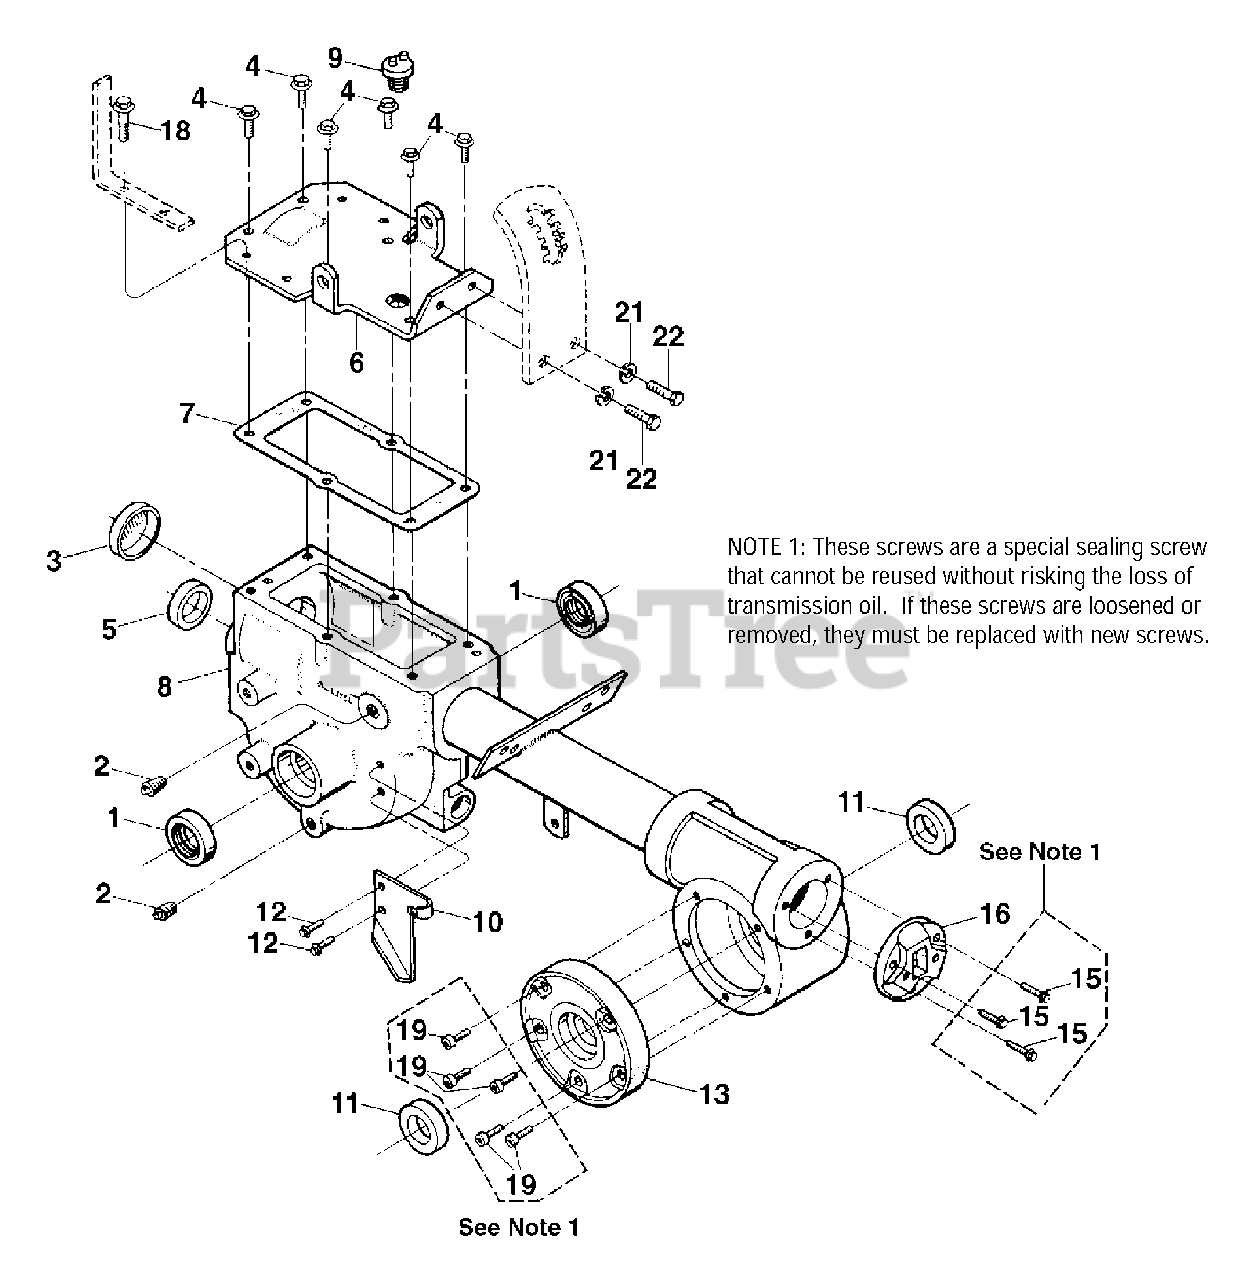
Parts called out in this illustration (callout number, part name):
1	Oil Seal (Double Lip), Wheel Shaft
2	Pipe Plug, 1/4,
3	Seal, Transmission Bore
4	Hex Flange Screw, 5/16-18 x 3/4
5	Oil Seal, Input Pinion Shaft
6	Transmission Cover
7	Gasket, Transmission Top Cover
8	Transmission Case Assy
10	Mounting Plate, Wheel Clutch Cable
11	Oil Seal, Tiller Shaft
12	Housing Cover, left side
15	Self-Sealing Screw, 1/4-20 x 7/8
16	Rear Bearing Cap
17	Gasket, Rear Bearing Cap, .010" Thick
18	Hex Flange Screw, 5/16-18 x 1
19	Self-Sealing Screw, 1/4-20 x 5/8
21	Lockwasher, 3/8
22	Hex Hd. Screw, 3/8-16 x 3/4
